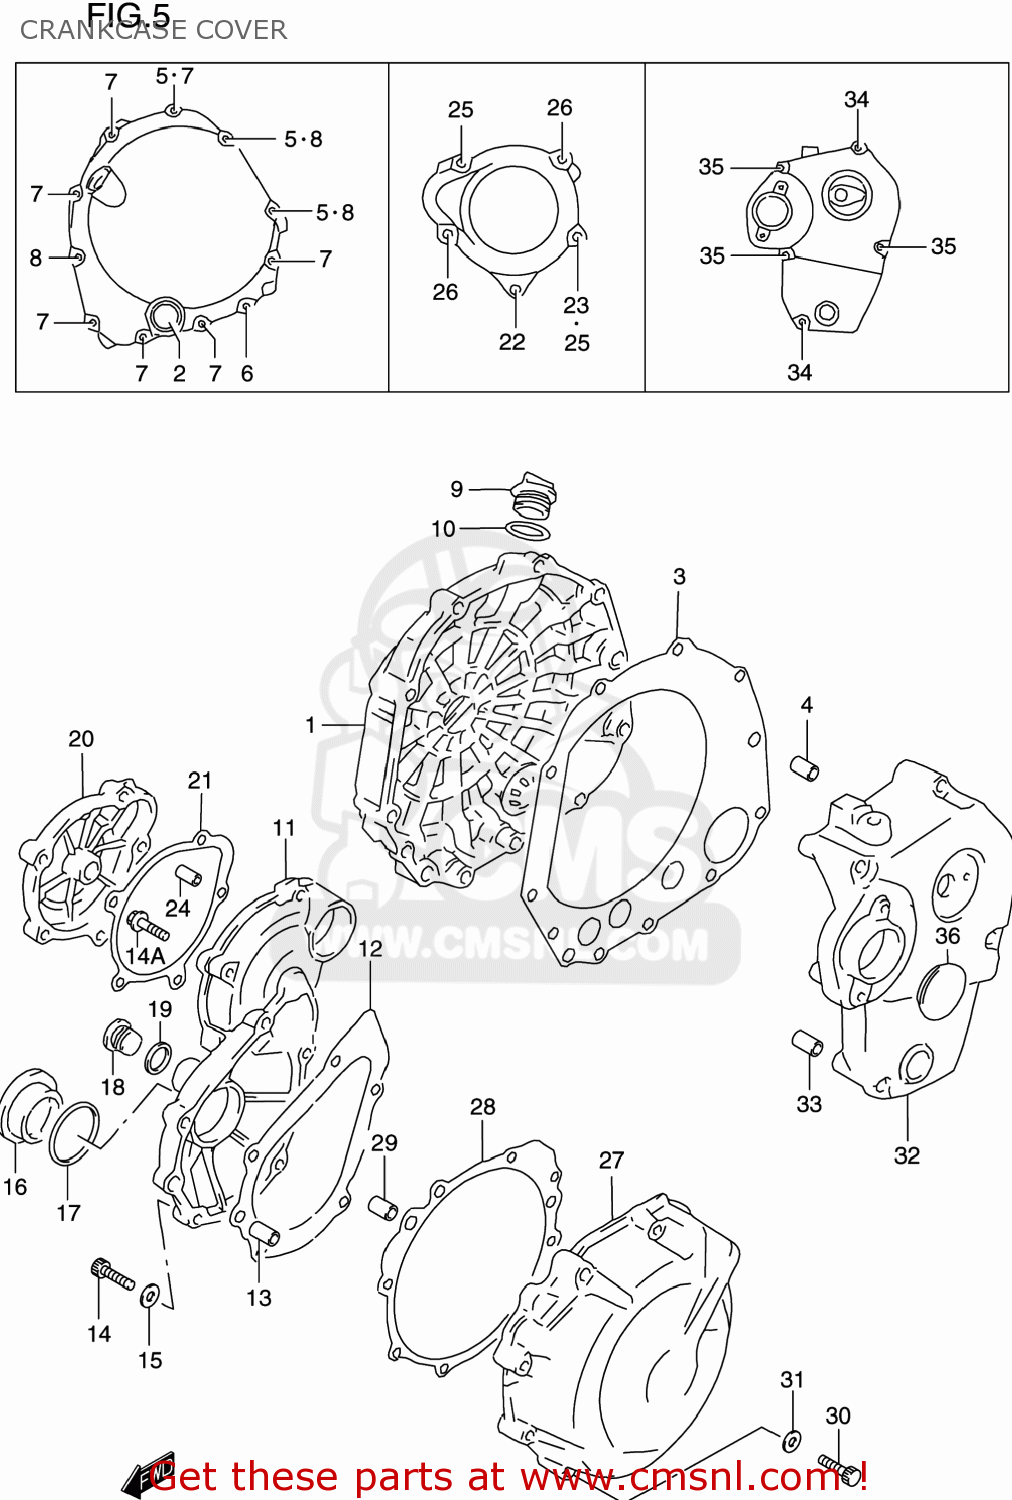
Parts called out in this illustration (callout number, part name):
1	COVER,CLUTCH
2	LENS,OIL LEVEL CHECK
3	GASKET,CLUTCH COVER (NAS)
4	PIN
5	GASKET(5.8X11X1.2) (NAS)
6	BOLT,OIL PAN
7	BOLT
8	BOLT
9	PLUG
10	O RING(D:3.1,ID:16.8)
11	COVER,STARTER CLUTCH
12	GASKET,STARTER CLUTCH COVER
13	PIN
14	BOLT,OIL PAN
14A	BOLT
15	GASKET(5.8X11X1.2) (NAS)
16	PLUG(SILVER)
17	O RING(D:3.1,ID:32.7)
18	PLUG
19	GASKET(16X22X2) (NAS)
20	CAP,STARTER IDLE GEAR
21	GASKET,START IDLE GEAR CAP (NAS)
22	BOLT
23	GASKET(5.8X11X1.2) (NAS)
24	PIN
25	BOLT,OIL PAN
26	BOLT
27	COVER,MAGNETO
28	GASKET,MAGNETO COVER (NAS)
29	PIN
30	BOLT
31	GASKET(5.8X11X1.2) (NAS)
32	COVER,ENGINE SPROCKET
33	PIN
34	BOLT
35	BOLT
36	CAP(OD:36)
